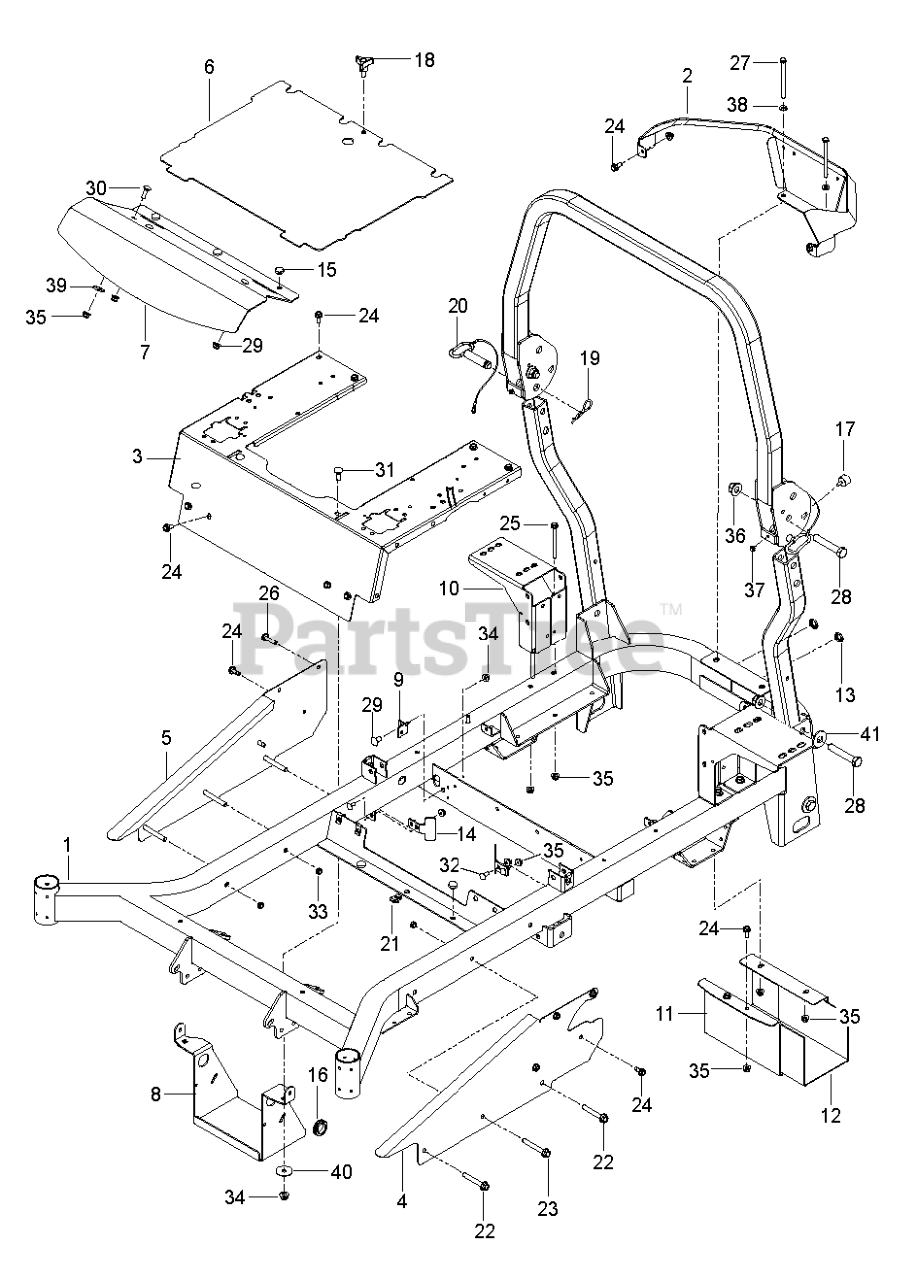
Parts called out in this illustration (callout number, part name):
1	KIT.FRAME.W/DECALS.X668
2	GUARD.PNT.REAR.MZ.GRAY
3	SUPPORT.PNT.SEAT.CONTROL.ORNG
4	SIDE.LT.ORANGE
5	SIDE.RT.ORANGE
6	PLATE, FLOOR W/DECALS
7	PLATE, FOOTREST
8	BRACKET BATTERY BLACK MS-431
9	BRACKET.DAMPENER.BLACK
10	MOUNT, TANK, ZT BLK
11	SHIELD.MUFFLER.BLACK
12	HEAT SHIELD
13	CAP.PLUG.BP-1.BLACK
14	STOP, DECK, EZ+
15	GROMMET, BUMPER
16	RUBBER GROMMET
17	U-CLIP 5/16-18 NUT RETAINER
18	KNOB W/STUD
19	WASHER
20	WASHER 1/2" FLAT
21	WASHER.13/32X1-1/2X16GA
22	HHFS 3/8-16 X 2.5 GR 5 ZD
23	HHFS 3/8-16 X 2-3/4 GR5 ZD
24	HHFS 5/16-18 X 3/4
25	BOLT.HEX.FLNG.5/16-18X3.75
26	HHFS 5/16-18 X 1.25 TPBLT GD 5
27	HCS 5/16C X 4
28	BOLT 5/16C X 3/4" CARRIAGE
29	RHSNB 3/8-16 X 3/4 GR 5 BLK ZN
30	RHSNB 5/16C X 1
31	RHSNB 3/8C X 1
32	5/16-18 NYLOC FLANGE NUT
33	NUT HEX 3/8-16 NYLON, THIN
34	NUT 3/8-16 HEX FLG NYLOC ZD
35	5/16-18 NYLOC FLANGE NUT
36	NUT 5/8-11 FLG NYLOC ZD
37	NUT.1/4-20.HEX.NYLOC.ZD
38	WASHER
39	WASHER 1/2" FLAT
40	WASHER.13/32X1-1/2X16GA
41	WASHER, 5/8 FLAT
